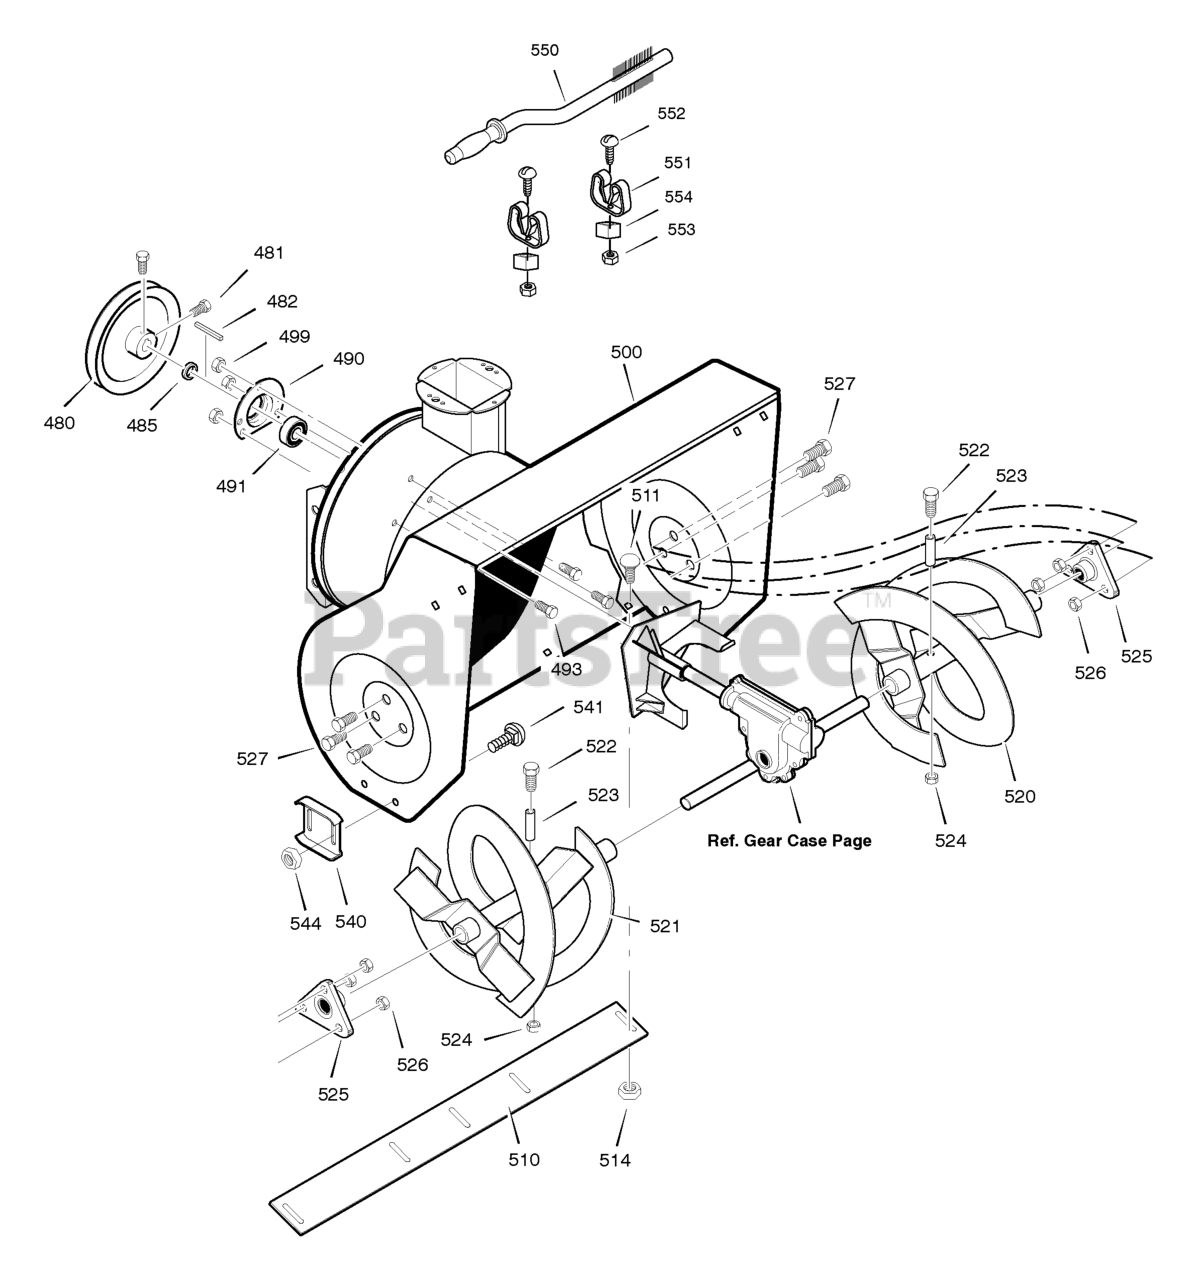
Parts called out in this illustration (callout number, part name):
480	PULLEY, 4L 6.12X .67
481	SCREW, 5/16-18 x 0.63
482	KEY, SQUARE 3/16 X 3/4
485	SPACER, FRICTION PULLEY
490	RETAINER, BALL BRNG
491	BEARING, BALL
493	BOLT, HEX 5/16-18X .50
499	NUT, 5/16-18 HEXWDFLLK
500	HOUSING, ASSY
510	BLADE, SCRAPER
511	BOLT, 1/4-20X.75
514	NUT, 1/4-20
520	AUGER, ASSY, LH
521	AUGER, ASSY, RH
522	SCREW, 1/4-20X1.75
523	SPACER, SLEEVE
524	NUT, 1/4-20
525	BEARING,FLANGE
526	NUT, 5/16-18
527	SCREW, 5/16-18 x 0.75
540	SKID, HEIGHT ADJUST
541	BOLT, 5/16-18 X .75
544	NUT, 5/16-18
550	BRUSH, CLEANOUT
551	CLIP, RETAINER
552	SCREW
553	NUT
